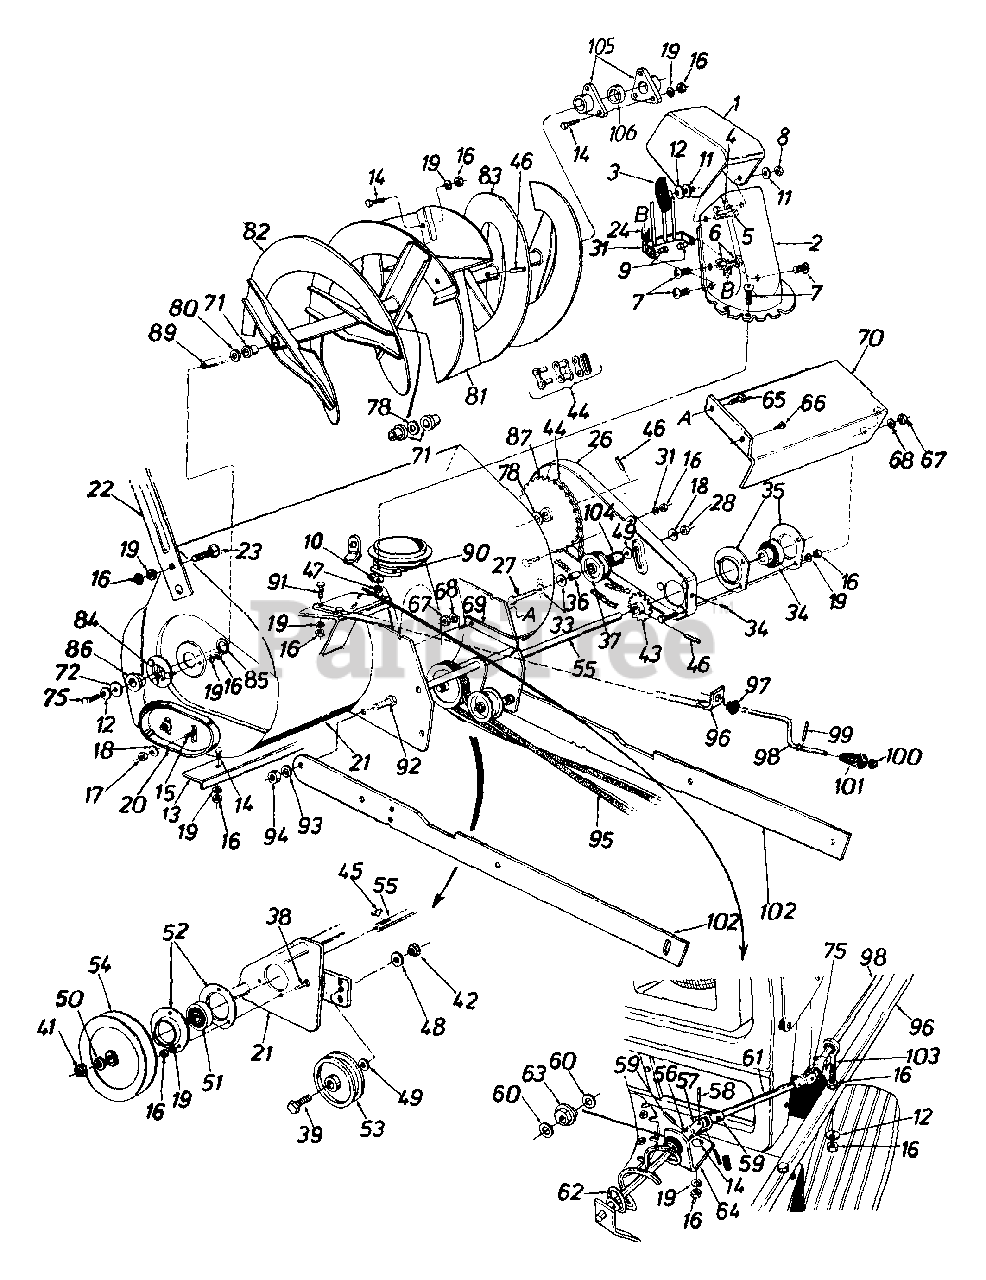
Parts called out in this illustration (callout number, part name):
1	Upper Chute
2	Lower Chute
3	Knob Handle Ass'y.
4	Truss Mach. Scr. 5/16-18 x .75" Lg.
5	Carriage Bolt 5/16-18 x 1" Lg.
6	Hex Cent. L-Nut 5/16-18 Thd.
7	Truss Mach. Scr. 1/4-20 x .75" Lg.
8	Hex Cent. L-Nut 5/16-18 Thd.
9	Shld. Nut 1/4-20 Thd.
10	Fl-Wash. 1/4" I.D.
11	Fl-Wash. .344" I.D. x 1.125"
12	Bell-Wash. .345" I.D. x .88"
13	Shave Plate
14	Carriage Bolt 5/16-18 x .62" Lg.
15	Carriage Bolt 3/8-16 x .62" Lg.
16	Hex Nut 5/16-18 Thd.
17	Hex Jam Nut 3/8-16 Thd.
18	Bell-Wash. .40" I.D. x .88"
19	L-Wash. 5/16" I.D.
20	Slide Shoe
21	Spiral Hsg. Ass'y.- 36"
22	Guide Blade
23	Carriage Bolt 5/16-18 x .62"
24	Extension Spring
26	Chain Guard Ass'y.
27	Hex Bolt 3/8-16 x 2" Lg.
28	Hex Ins. Nut 3/8-16 Thd.
31	Chute Guard Ass'y.
33	Fl-Wash. .385" I.D. x .87" O.D.
34	Ball Brg. .75" I.D.
35	Flangette
36	Spacer .375" I.D. x .60" O.D.
37	Flat idler 1.875" Dia.
38	Hex Sems Bolt 5/18 x .75" Lg.
39	Hex Bolt 3/8-16 x 1.75" Lg.
41	Hex Jam Nut 3/4-10 Thd.
42	Hex Jam Nut 3/8-16 Thd.
43	Sprocket Ass'y. - 14 Teeth
44	#420 Chain x 1/2" Pitch - 77 Links
44	Master Link
45	#61 Hi-Pro-Key 3/16 x 5/8"
46	Spring Pin Spir. 5/16" Dia. x 1.75" Lg.
47	Hex L-Nut 1/4-20 Thd.
48	L-Wash. 3/8" I.D.
49	Fl-Wash. .406" I.D. x 1.25"
50	Spr. L-Wash. 3/4" I.D.
51	Self-Aligning Brg.
52	Flangette
53	Idler Pulley
54	5/8 V-Pulley .75" I.D. x 6" O.D.
55	Drive Shaft Ass'y.
56	Joint Brkt. Ass'y.
57	Joint Block
58	Oval Head Rivet
59	Spiral Pin 1/8" Dia.
60	Fl-Wash. .385" I.D. x .62"
61	Chute Crank Ext. Rod
62	Chute Crank Ass'y. R.H.
63	Plastic Bushing .38" I.D.
64	Chute Crank Brkt.
65	Hex Bolt 1/4-20 x .62" Lg.
66	Hex Wash. S-Tap Scr. 1/4-20 x .50" Lg.
67	Hex Nut 1/4-20 Thd.
68	L-Wash. 1/4" I.D.
69	Belt Cover
70	Drive Shaft Cover
71	Plastic Bushing
72	Washer .39" I.D. x 1.75" O.D.
73	Hex Bolt 5/16-18 x .88" Spec.
75	Cotter Pin 3/32" Dia.
78	Fl-Wash. 1.03" I.D. x 1.62"
80	Fl-Wash. 1" I.D. x 1.75"
81	Rotor Paddle Ass'y.
85	Snap Ring for 1.5" Shaft
86	Flange Brg. w/flats 1" I.D.
87	Sprocket Hub Ass'y. 40 Teeth
89	Spiral Axle
90	Chute Flange Keeper
91	Hex Bolt 5/16-18 x 1.5" Lg.
92	Hex Bolt 1/2-13 x 1.25" Lg.
93	L-Wash. 1/2" I.D.
94	Hex Nut 1/2-13 Thd.
95	V-Belt
98	Chute Crank 34.5" Lg.
99	Roll Pin .12" Dia. x .63"
100	Push Nut 3/8" Rod
101	Knob Black
102	Linkage Arm
103	Eye Bolt 5/16-18 x 3" Lg.
104	Idler Spacer
105	Bearing
106	Ball Bearing
